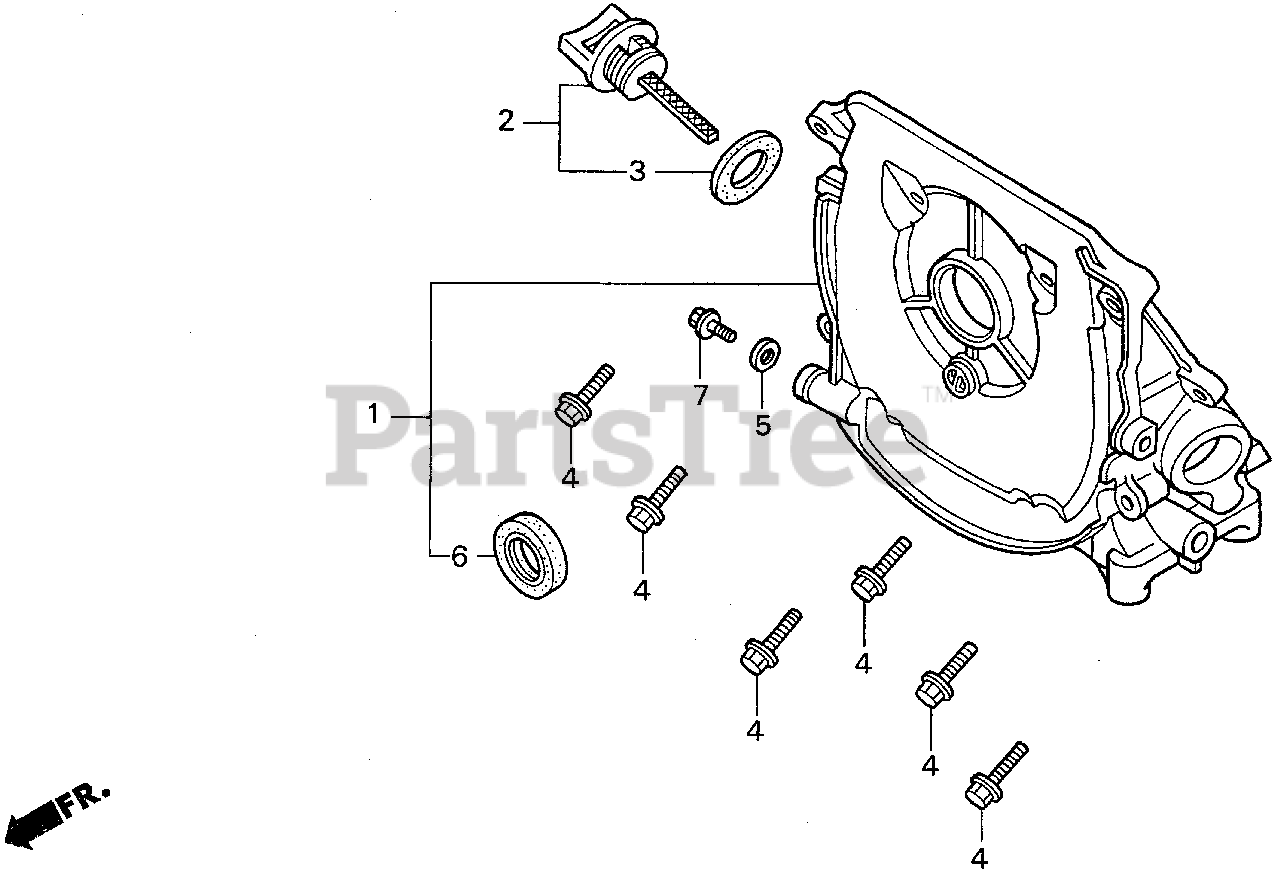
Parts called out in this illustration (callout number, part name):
1	CASE ASSY., OIL
2	CAP ASSY., OIL FILLER
3	GASKET, OIL FILLER CAP
4	BOLT, FLANGE (5X23)
5	WASHER (8MM)
6	OIL SEAL (17X27X5) (KOYO)
7	BOLT, FLANGE (8X12)
